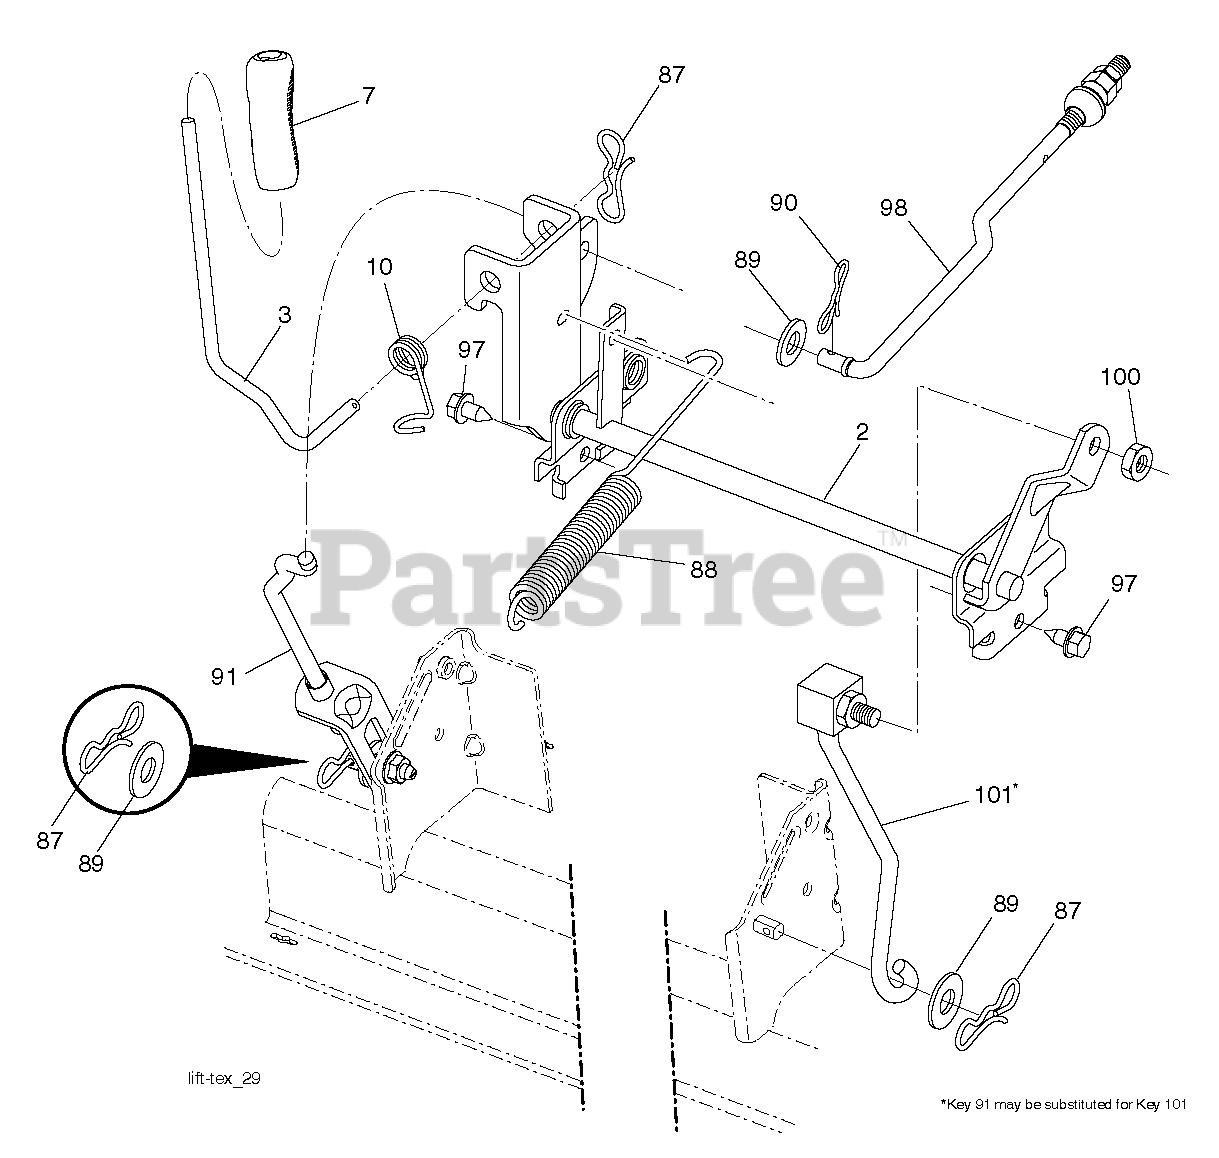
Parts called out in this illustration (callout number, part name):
2	SHAFT.ASM.CROSS.LIFT
3	LEVER.LIFT.HANDLE.LT
10	SPRING.TORSION.LIFT.HANDLE
87	PIN.COTTER.7/16.BOW TI
88	SPRING.LIFT.ASSIST
89	WASHER.CLEAR.ZINC
90	PIN.COTTER.5/16.BOW TI
91	LINK.ASM.LIFT.REAR
97	SCREW, 3/8-16X3/4
98	LINK.ASM.SUSP.FRONT.MW
100	LOCKNUT
101	LINK.ASM.LIFT.FIXE.38/42/46"
